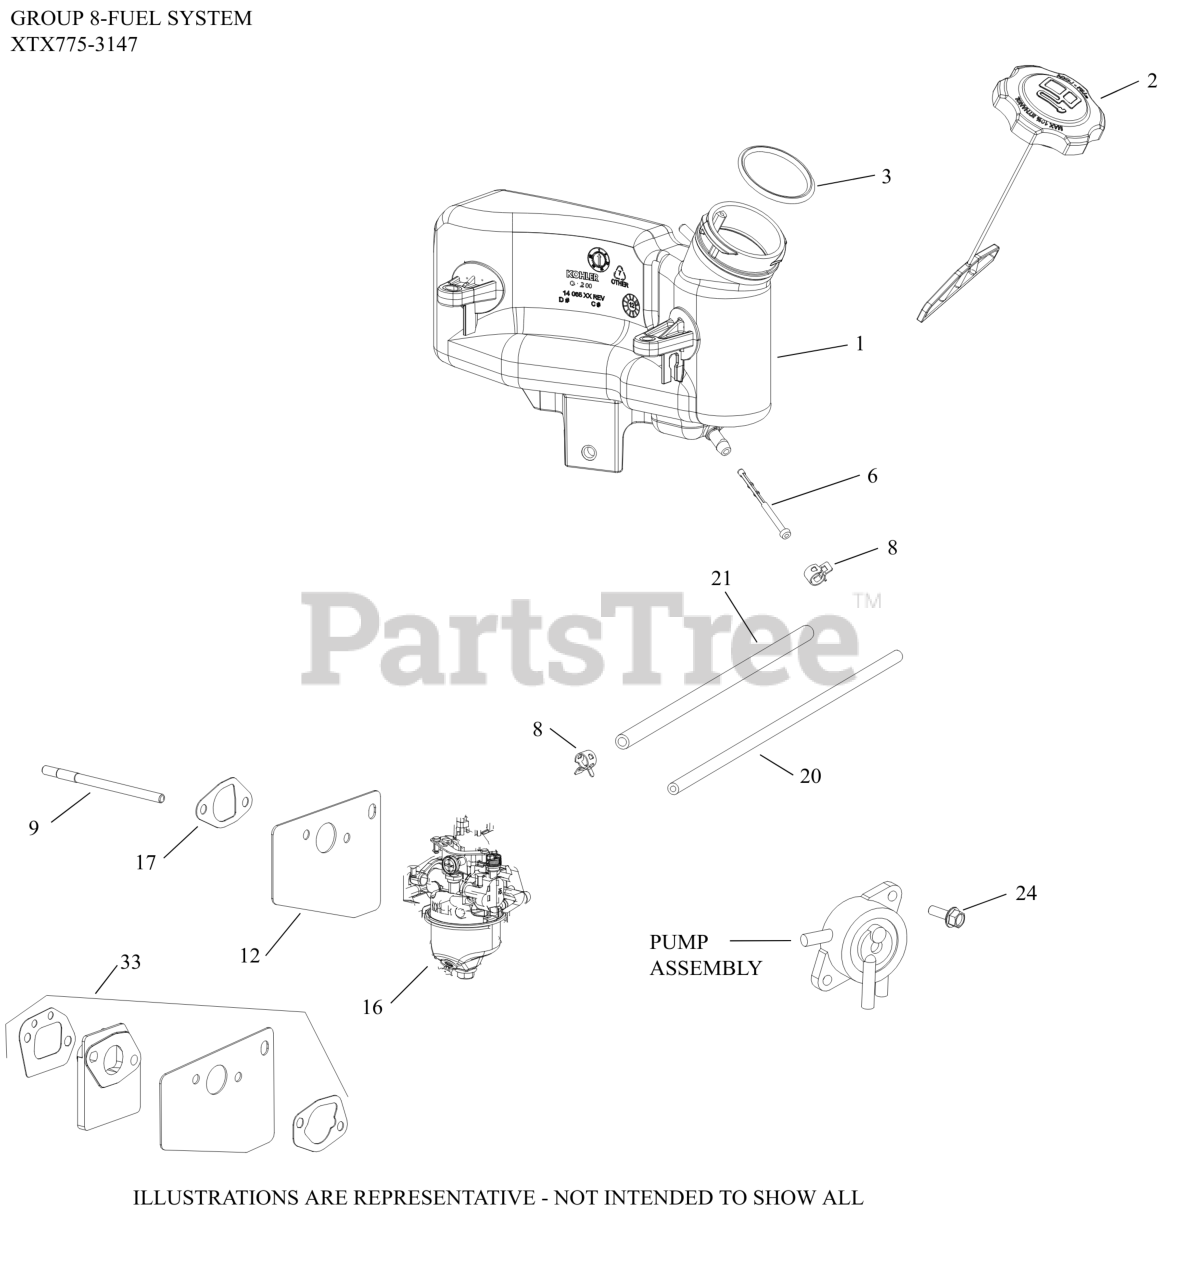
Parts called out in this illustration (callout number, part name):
1	TANK, FUEL
2	CAP ASSEMBLY, FUEL
3	SEAL, FUEL CAP
6	FILTER, FUEL IN-NIPPLE
8	CLAMP, HOSE (NON-CALIF)(#1423710S)
9	STUD, M6X1.0X93.8MM
12	KIT, CARBURETOR HEAT SHIELD GASKET
16	KIT, CARBURETOR 13 MM STD CHOKE
17	KIT, INTAKE GASKET
20	HOSE, EVAPORATIVE
21	HOSE, FUEL LOW-PERMEATION
24	SCREW, HEX FLANGE (M6)
33	KIT, CARBURETOR SPACER
NI	KIT, HIGH ALTITUDE - USE 14 755 04-S
NI	KIT, CARBURETOR REPAIR (RUIXING)
